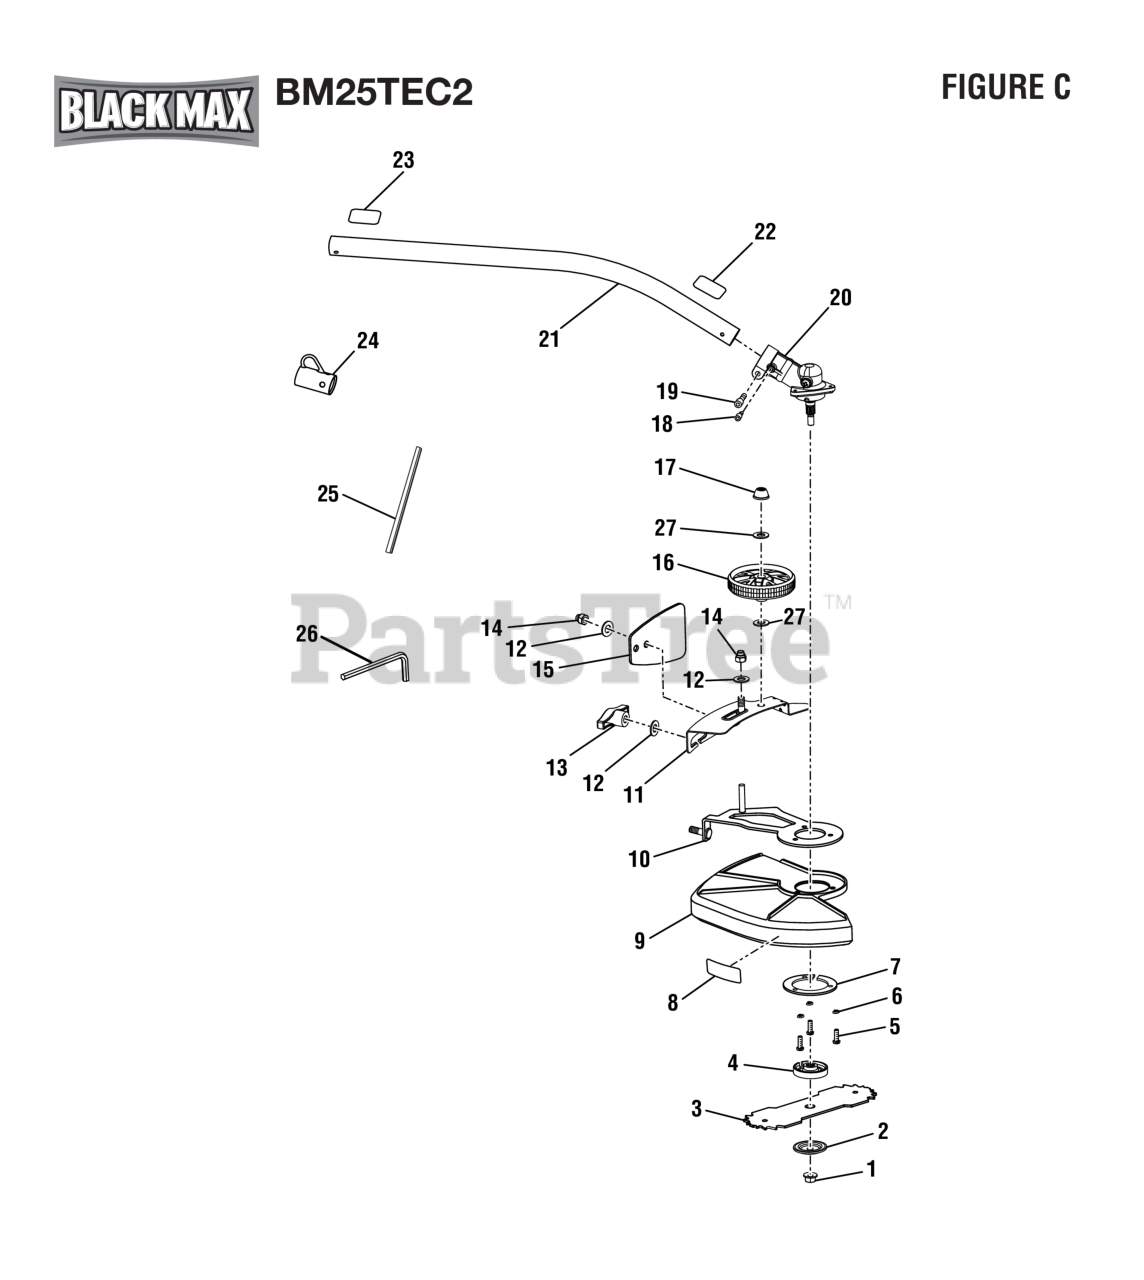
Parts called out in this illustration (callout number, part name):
1	Lock Nut (M8 x 1.25 in., Left Hand Threads)
2	CUPPED WASHER
3	Edger Blade
4	FLANGED WASHER
5	Screw (10-24 x 5/8 in, Hex Hd.)
6	Lock Washer (5 mm)
7	Ring Washer
8	Warning Label (Guard)
9	Blade Guard
10	Main Frame
11	Wheel Frame
12	Washer (10 mm)
13	Adjusting Knob w/Hex Nut
14	Hex Nut with Nylon Cap (5/16-18)
15	Debris Flap
16	Guide Wheel
17	Push Nut (10 mm)
18	Screw (10-24 x 5/8 in. Hex Socket Hd.)
19	Screw (1/4-20 x 1-1/4 in., Hex. Socket Hd.)
20	Gear Head Assembly
21	Drive Shaft Assembly
22	Hot Surface Warning Label
23	Boom Icon Warning Label
24	Hanger Cap
25	Gear Head Locking Tool
26	Hex Key (M4)
27	Washer, ID 11 x OD 18 x 2T
